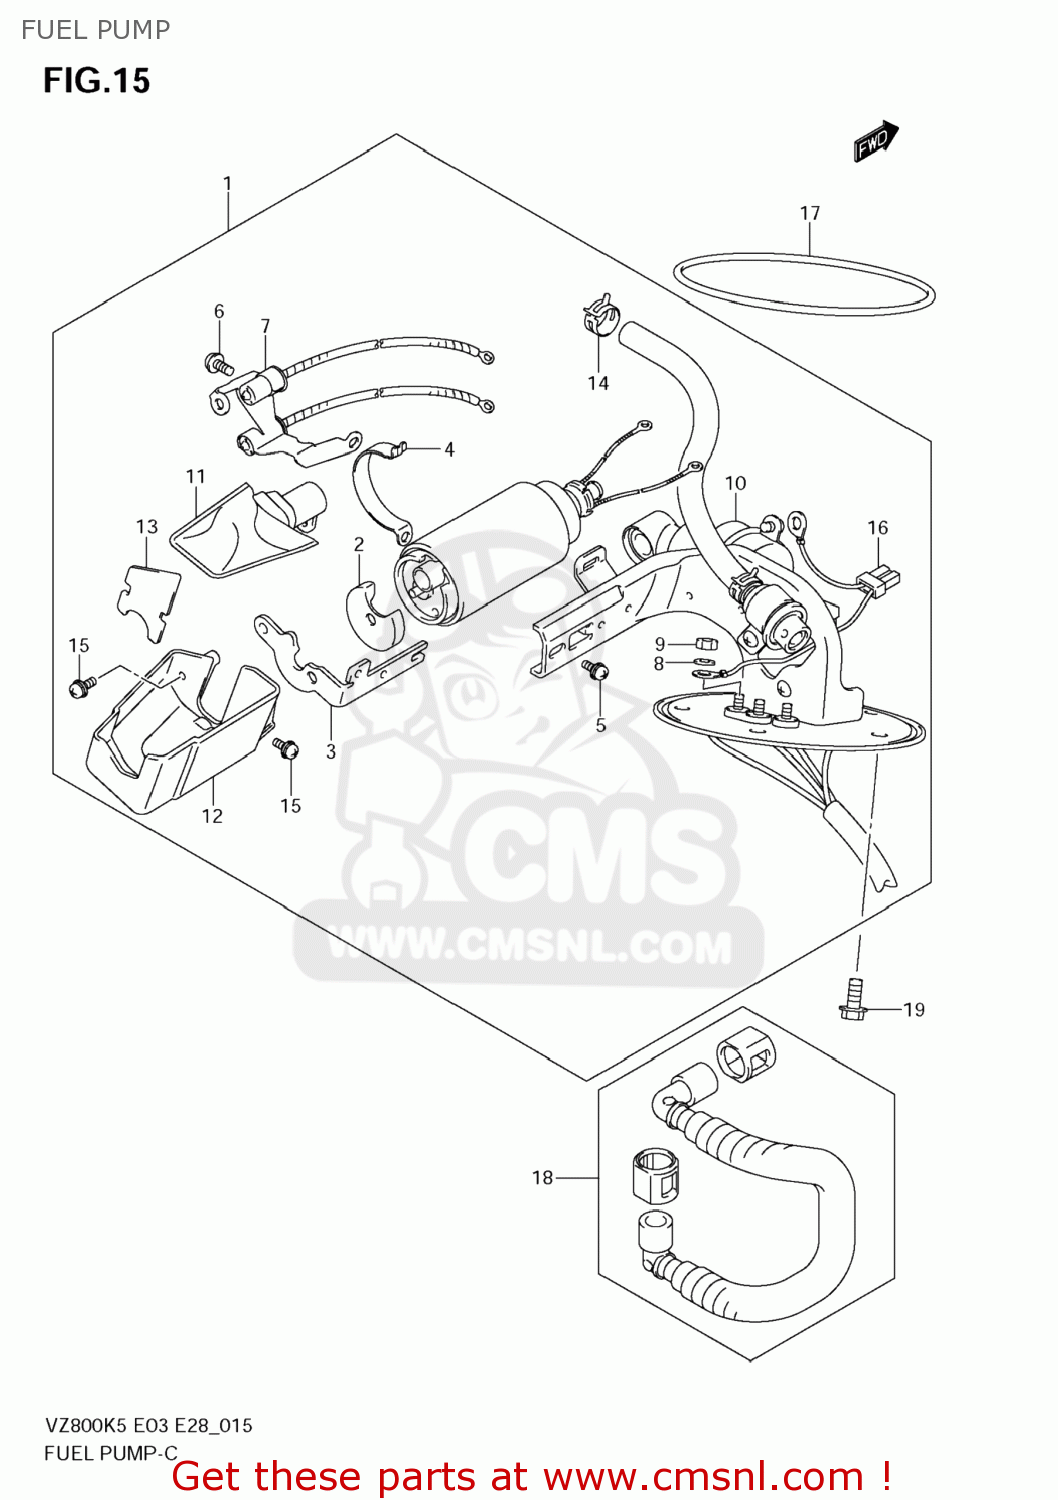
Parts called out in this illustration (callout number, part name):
1	PUMP ASSY,FUEL
2	CUSHION
3	HOLDER
4	BAND,FUEL PUMP
5	SCREW
6	SCREW
7	THERMISTOR
8	WASHER,SPRING
9	NUT
10	PLATE ASSY
11	STRAINER,FUEL
12	VESSEL
13	COVER
14	CLIP
15	SCREW
16	HARNESS
17	O RING,FUEL PUMP
18	HOSE,FUEL
19	BOLT
